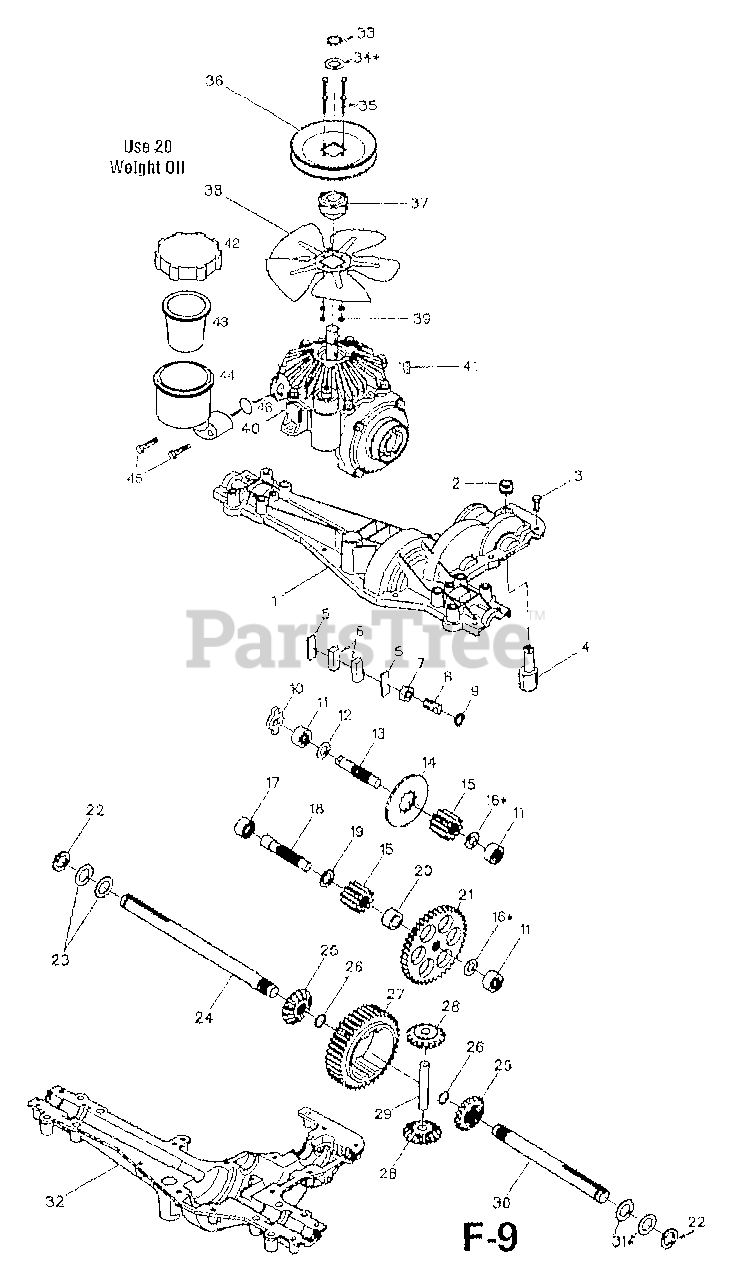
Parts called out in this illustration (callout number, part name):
1	HOUSING-UPPER
2	RING-V
3	SCR-SELF TAP 1/4-20X.734
4	ASSM-SHAFT & CAM
5	SPACER
6	BLOCK FRICTION
7	NUT-HEX/JAM
8	ADJUSTMENT-STUD
9	RING-O
10	KEY-DRIVE
11	ASSM-BEARING
12	WASHER-.505 X .942 X .040
13	SHAFT-INPUT
14	BRAKE-DISC
15	SPUR-GEAR 10T
16	KIT-SHIM (.500 SHAFT)
17	ASSM-BEARING
18	SHAFT-IDLER
19	WASHER-.632 X 1.0 X .041
20	SPACER .630 X 1.00 X .549
21	SPUR-GEAR 41T
22	WASHER-NEOPRENE
23	WASHER-.758X1.25X.031
24	AXLE-TRANSMISSION LH
25	MITER-GEAR 15T
26	RING-RETAINING
27	SPUR-GEAR 41T
28	MITER-GEAR 15T
29	SHAFT-CROSS
30	AXLE-TRANSMISSION RH
31	KIT-SHIM (.750 SHAFT)
32	HSG-TRANSMISSION LOWER
33	RING-RETAINING
34	KIT-SHIM (.670 SHAFT)
35	SCR-HHC #6-32X.88
36	PULLEY-4.50" DIA
38	KIT-FAN
39	NUT-H/LK #6-32
40	ASSM-HYDROSTATIC
41	KEY-WOODRUFF
43	DIAPHRAGM
44	RESERVOIR
45	SCR-HFLK 1/4-20X1.00
